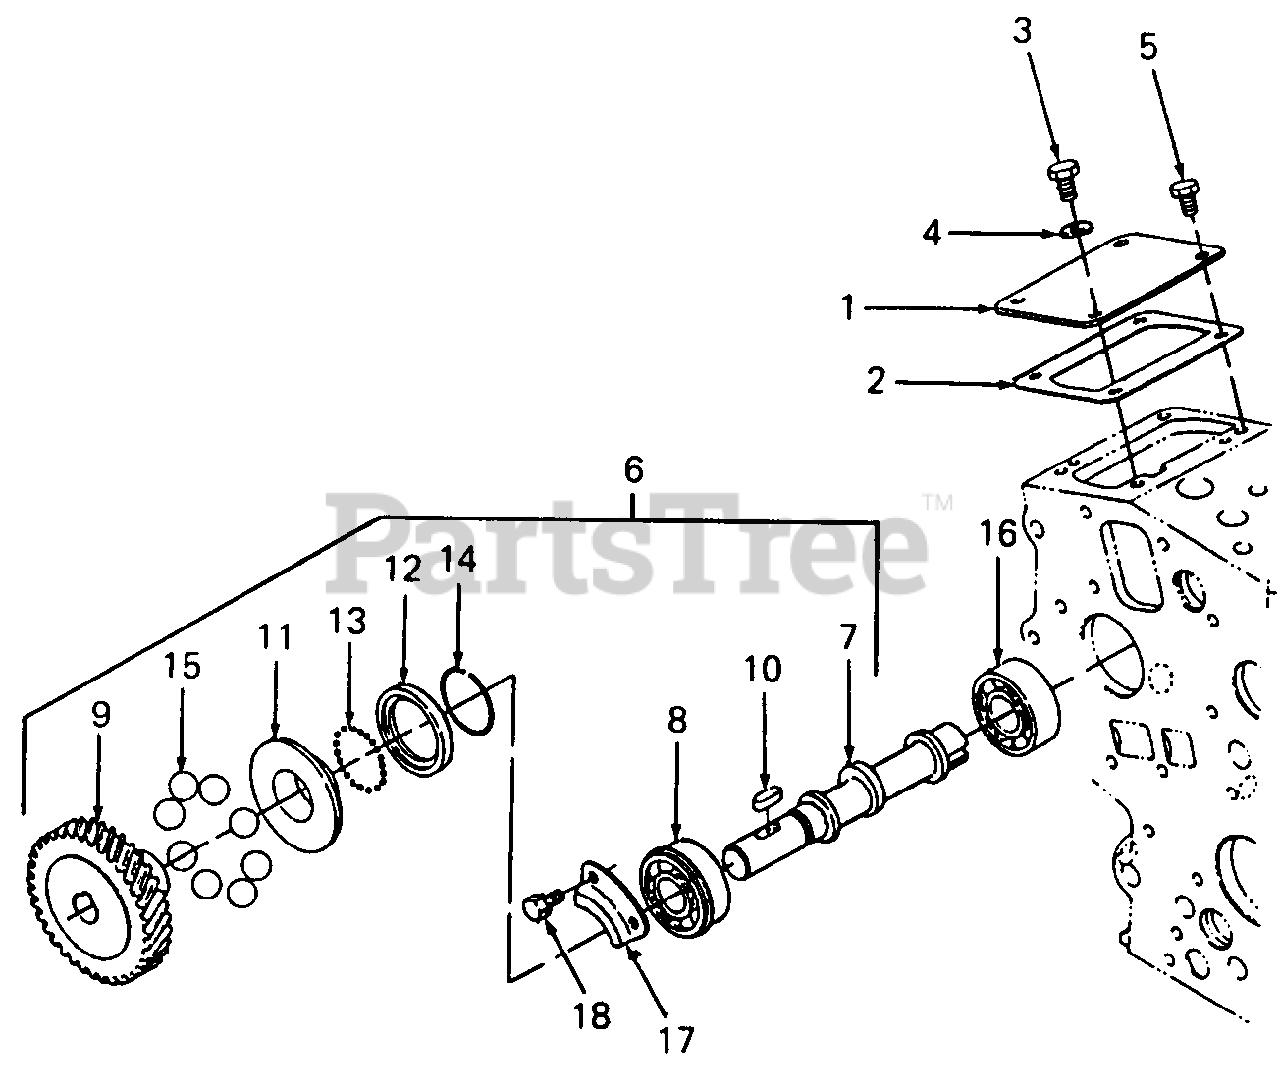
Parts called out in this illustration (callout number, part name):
7	Shaft, Distributor
8	Bearing, Ball
9	Gear, Injection Pump
11	Sleeve, Governor
12	Case, Governor Ball
14	Cir-Clip, Governor Sleeve
16	Bearing, Ball
